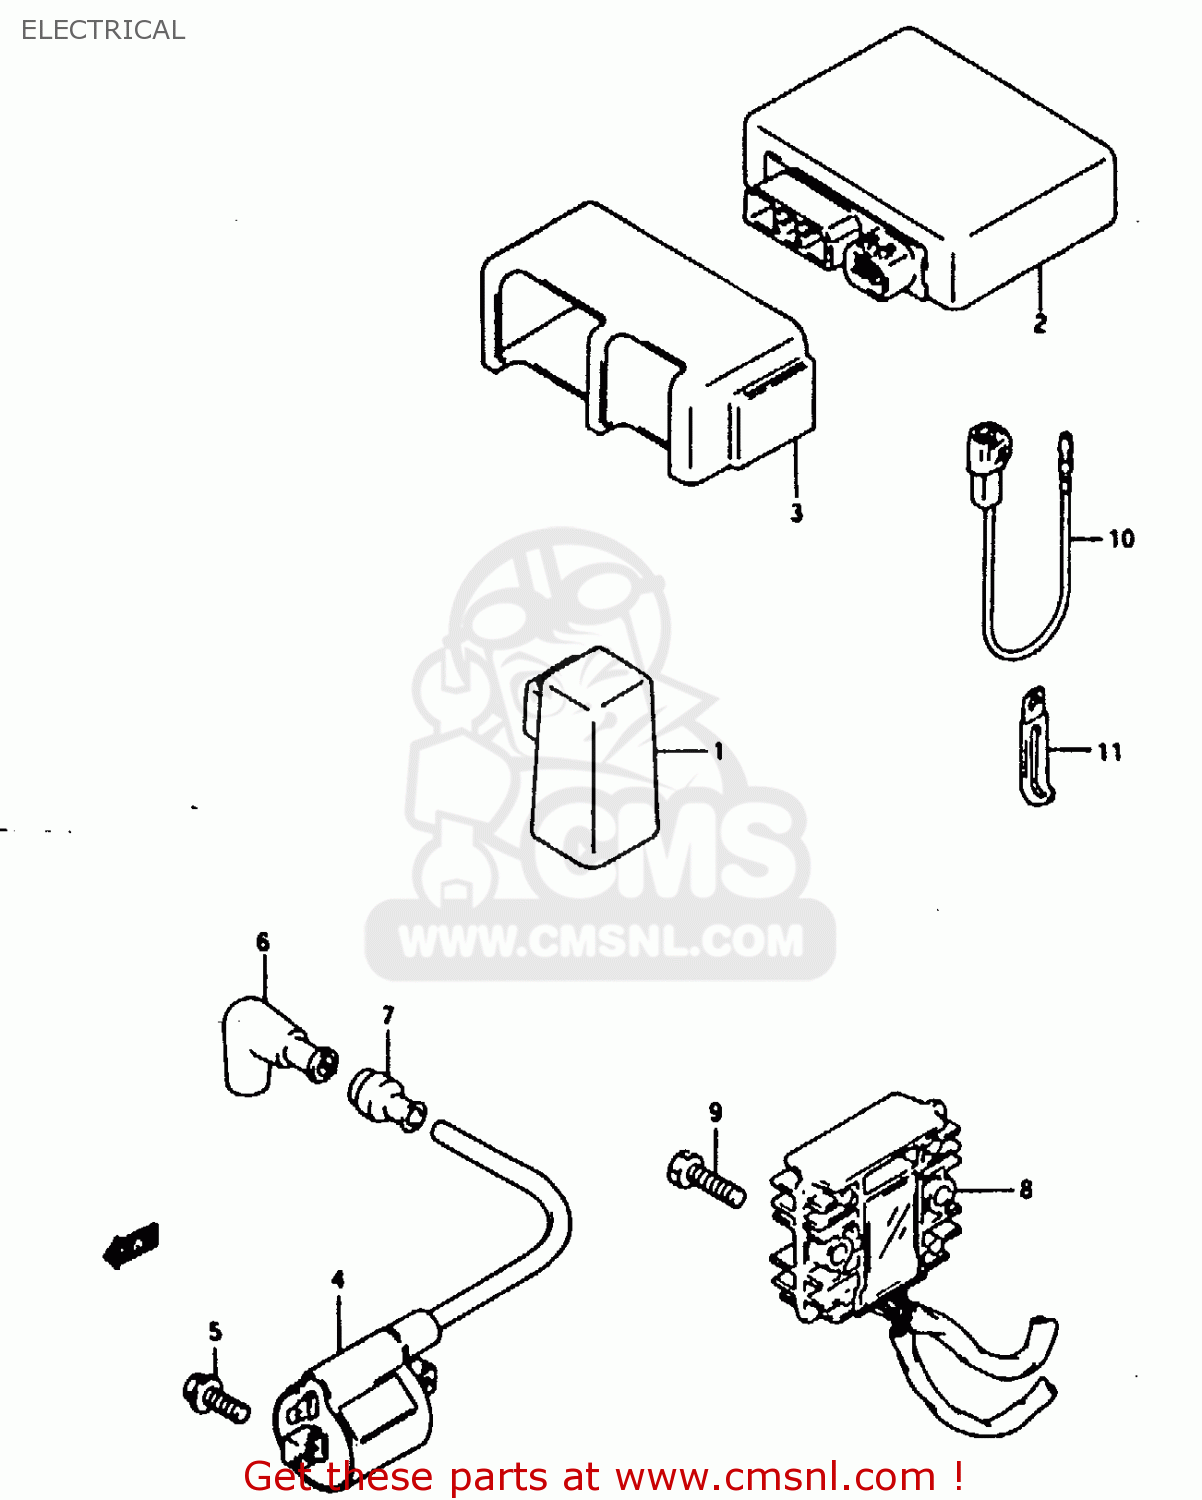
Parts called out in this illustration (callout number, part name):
1	RFLAY ASSY, STARTING MOTOR
2	CDI UNIT
3	HOLDER, CDI UNIT
4	COIL ASSY,IGNITION
5	BOLT
6	CAP,SPARK PLUG
7	SEAL,HIGH TENSION CORD
8	RECTIFIER ASSY
9	SCREW (6X25)
10	WIRE, NEUTRAL SWITCH LEAD
11	CLAMP
